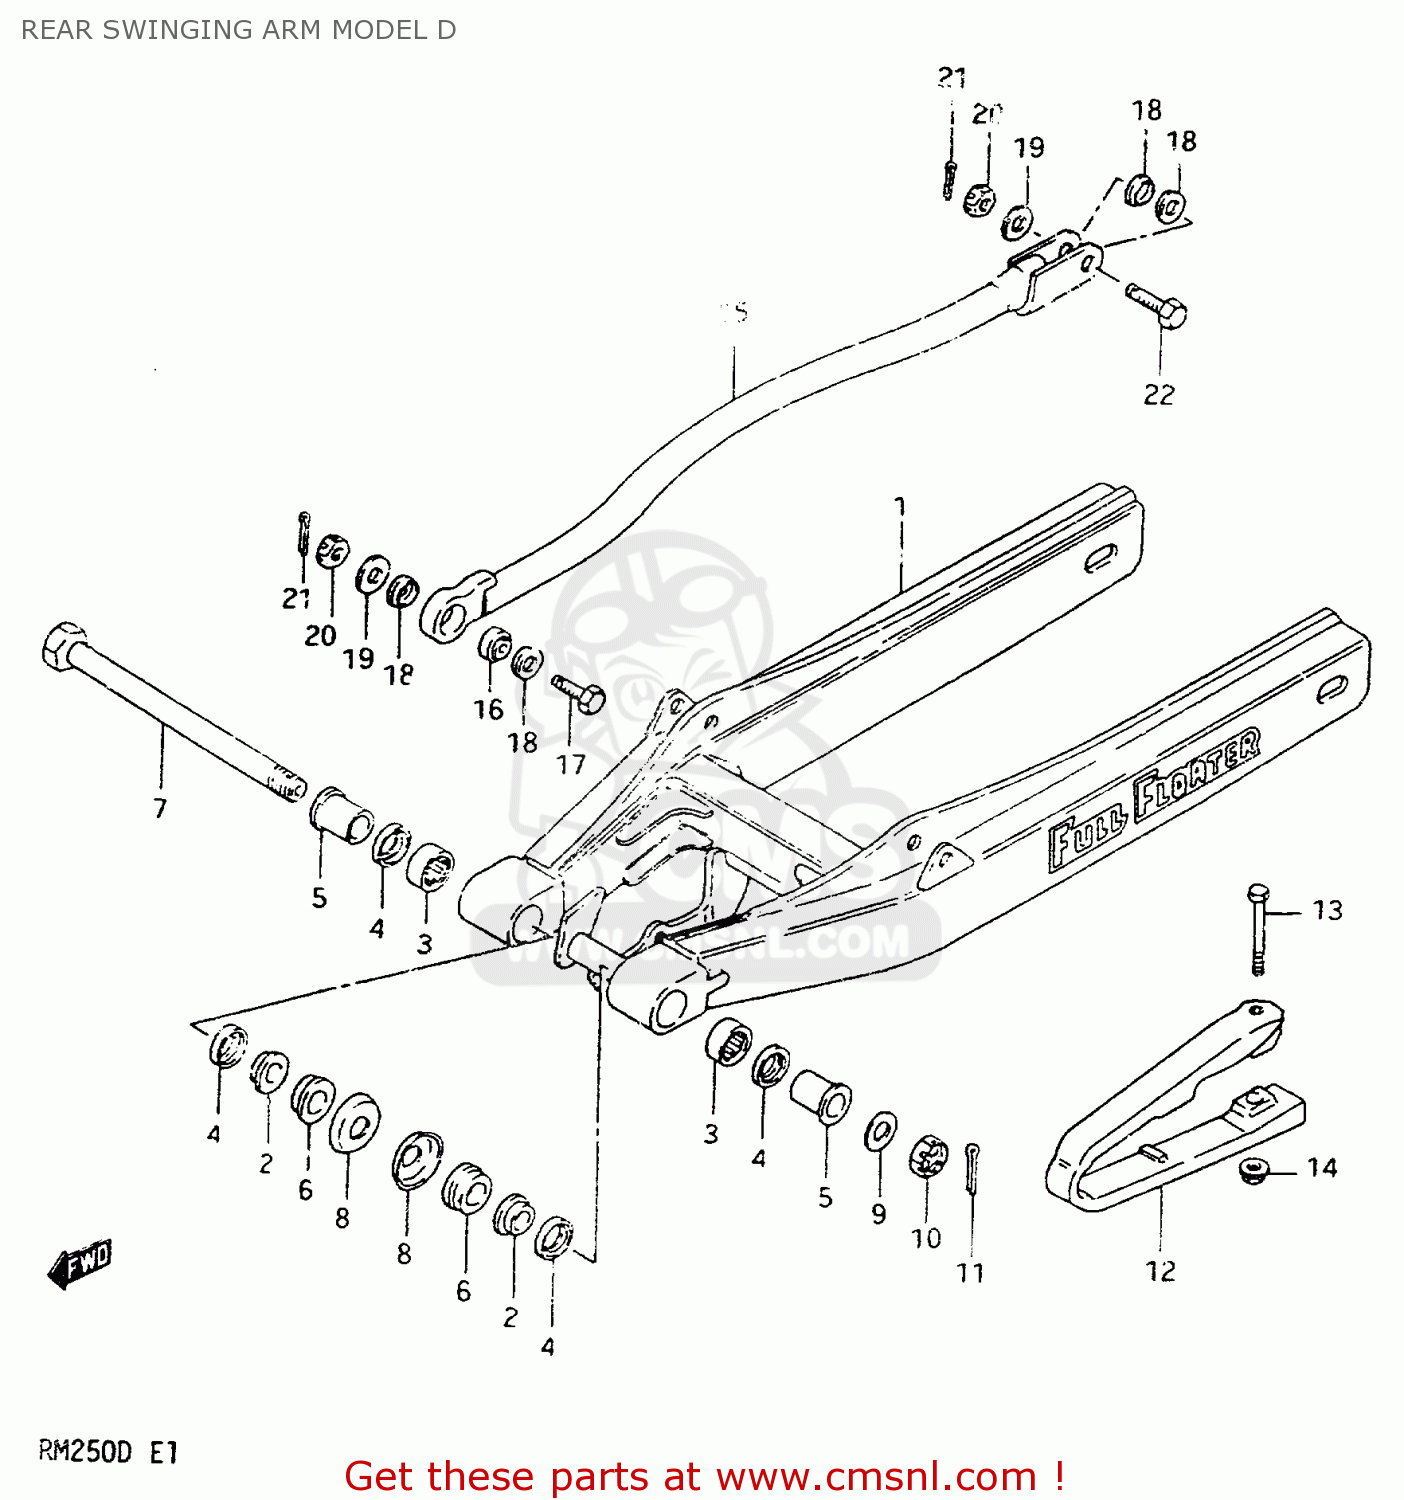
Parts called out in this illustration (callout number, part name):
1	SWING ARM ASSEMBLY,REAR
2	BUSHING,REAR SWING ARM PIVOT
3	BEARING(20X27X20)
4	OIL SEAL
5	SPACER,RR SWGARM PIVOT
6	SPACER,RR SWGARM PIVOT INNER
7	SHAFT,RR SWINGINGARM PIVOT
8	COVER,RR SWGARM DUST SEAL
9	WASHER
10	NUT 14MM
11	COTTER PIN
12	BUFFER,CHAIN TOUCH DEFENSE
13	BOLT(6X70)
14	NUT
15	TORQUE LINK SET,RR
16	SPHERICAL BEARING,TORQUE
17	BOLT 8X28
18	19
19	WASHER
20	NUT 8MM
21	PIN 20X20
22	BOLT 8X29.5
